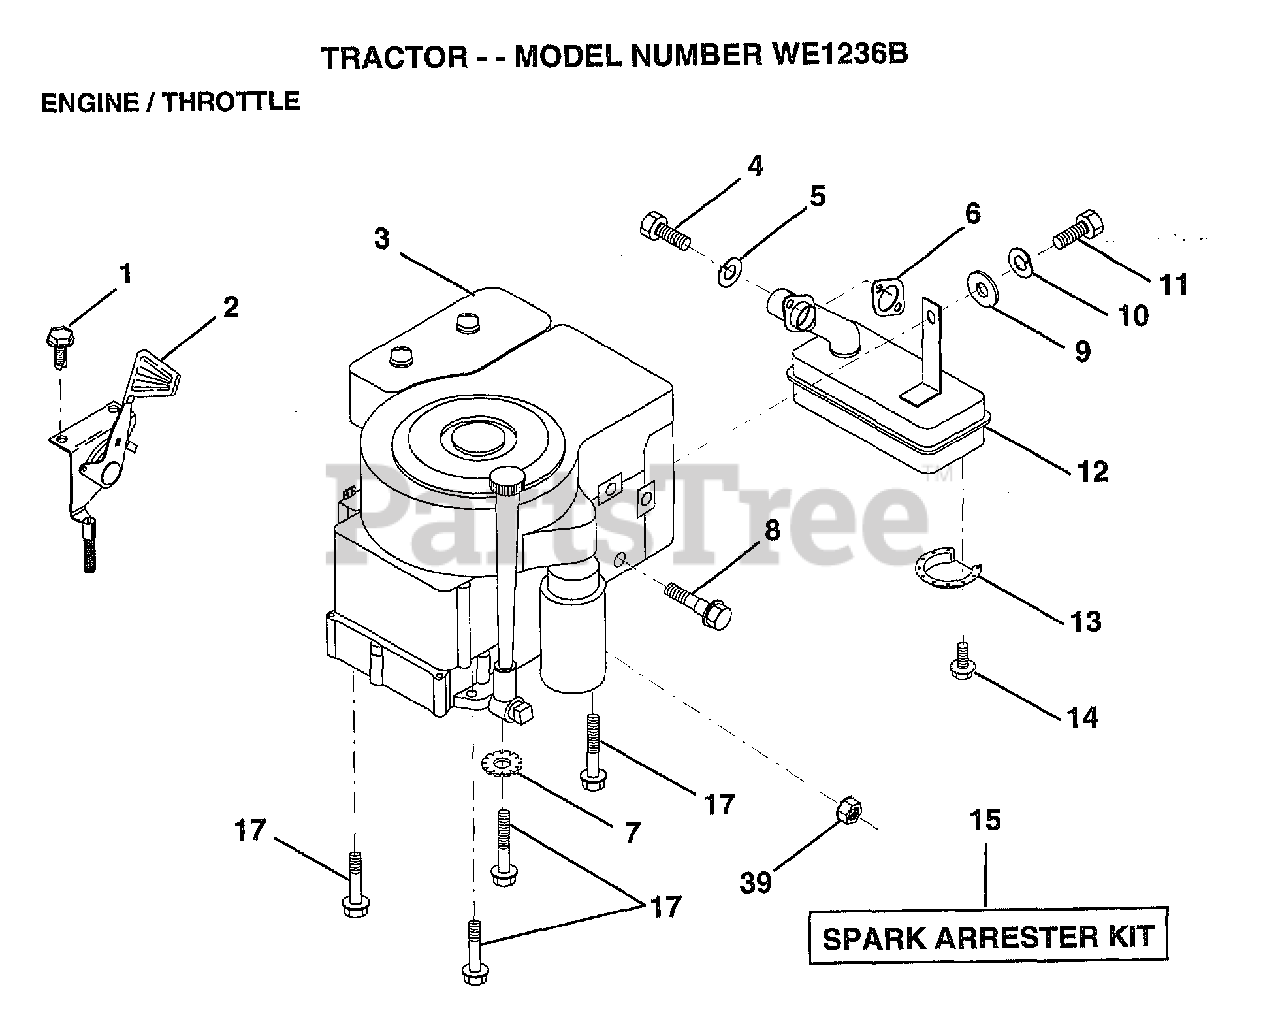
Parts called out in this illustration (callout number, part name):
1	SCREW.1/4-20X1/2
2	"CONTROL,THROTTLE"
3	ENG B&S 10-12.5HP PWRBLT DC
4	SCREW
5	LOCKWASHER
7	LOCKWASHER
8	BOLT T
10	LOCKWASHER
12	MUFFLER
13	DEFLECTOR.222573
17	SCREW LT
39	NUT
